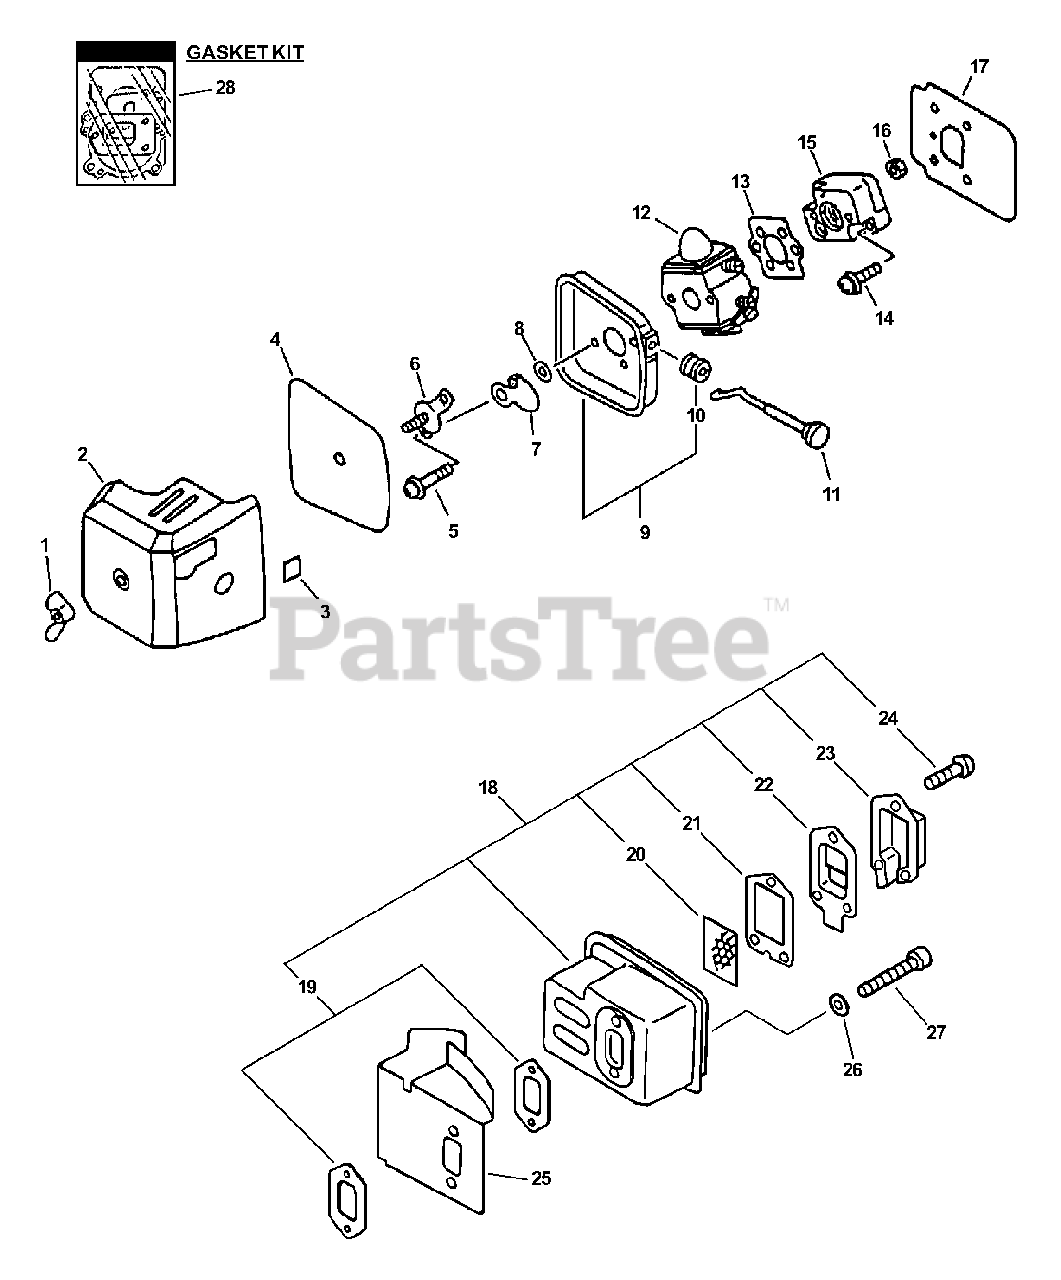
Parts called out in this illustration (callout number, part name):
1	WINGNUT - 6
2	COVER, AIR FILTER
3	LABEL, CHOKE
4	FILTER, AIR
5	SCREW 5×57
6	PLATE, PREVENT
7	SHUTTER, CHOKE
8	WASHER 5.2×8×0.8T
9	CASE, AIR FILTER
10	GROMMET, CHOKE
11	ROD, CHOKE
12	CARBURETOR - C1U-K54A
13	GASKET, INTAKE
14	SCREW 5×20
15	INSULATOR, INTAKE
16	NUT M5
17	HEAT SHIELD, INTAKE
18	MUFFLER ASSY
19	GASKET, EXHAUST
20	SCREEN, SPARK ARRESTER
21	GASKET, EXHAUST
22	GUIDE, EXHAUST
23	GUIDE, EXHAUST - INNER
24	SCREW 4×10
25	COVER, MUFFLER
26	WASHER, FLAT 5.5×10×0.8
27	BOLT M5×50
28	GASKET KIT
